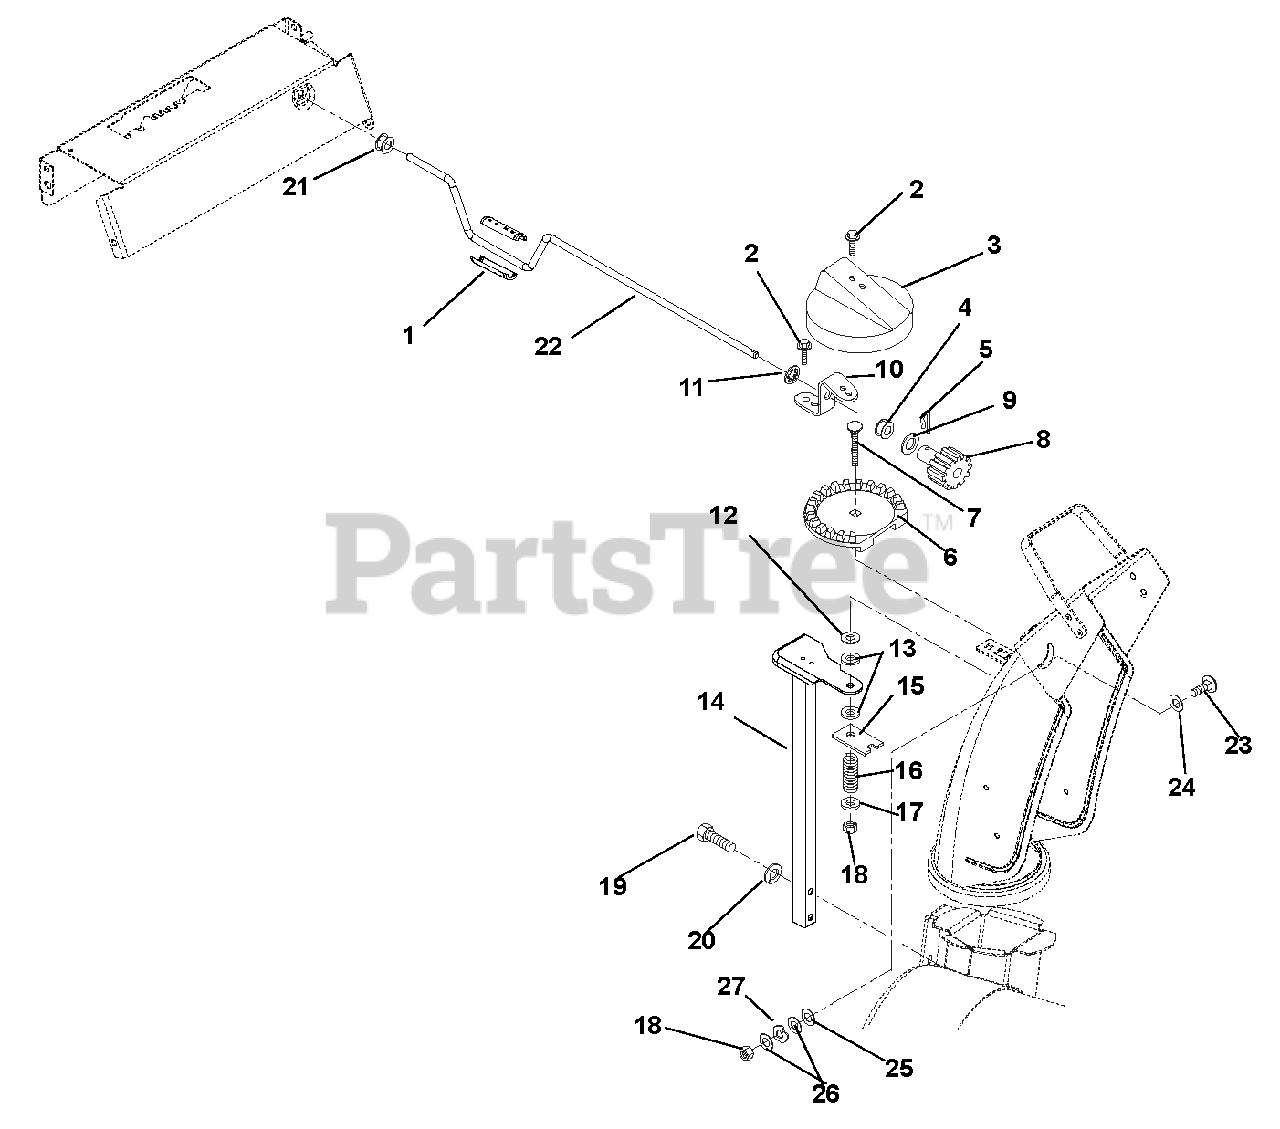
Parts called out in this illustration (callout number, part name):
1	KNOB, CRANK-SNAP
2	@SCR-TAP .25-20X.50 HWH TR YWZ
3	GEAR COVER
4	BUSHING, POLYLINER-.63 SNAPIN
5	PIN, SPRING CLIP
6	CHUTE GEAR
7	@BLT-RDHDSQNK .38-16X2.50 G5YZ
8	PINION GEAR W/BRACKET
9	WSHR-THRST .625 X 1.0 X .03
10	BRACKET, PINION GEAR
11	PUSHNUT .625
12	WSHR-FL-STL .380X1.50X.062 YWZ
13	FRICTION WASHER
14	PEDESTAL, CHUTE - CRANK
15	PLATE, FRICTION
16	SG-COMP .187X.56X1.62
17	@WSHR-FL-STL.406X.812X.065 YWZ
18	@NUT-LK-CTR .38-16 YWZC
19	@BLT-HEX .38-16X1.75 GR5 YWZC
20	@WSHR-LK .38X.094 REG YWZC
21	BUSHING, POLYLINER-.38 SNAPIN
22	ROD, CHUTE CRANK
23	@BLT-RHDSSQNK .38-16X.75 G5YZ
24	WSHR-FL-STL .52X.827X.062 YWZC
25	WSHR-PLASTIC .390X.875X.062
26	@WSHR-FL-STL.406X.812X.065 YWZ
27	WAVE WASHER .390X.655X.110
